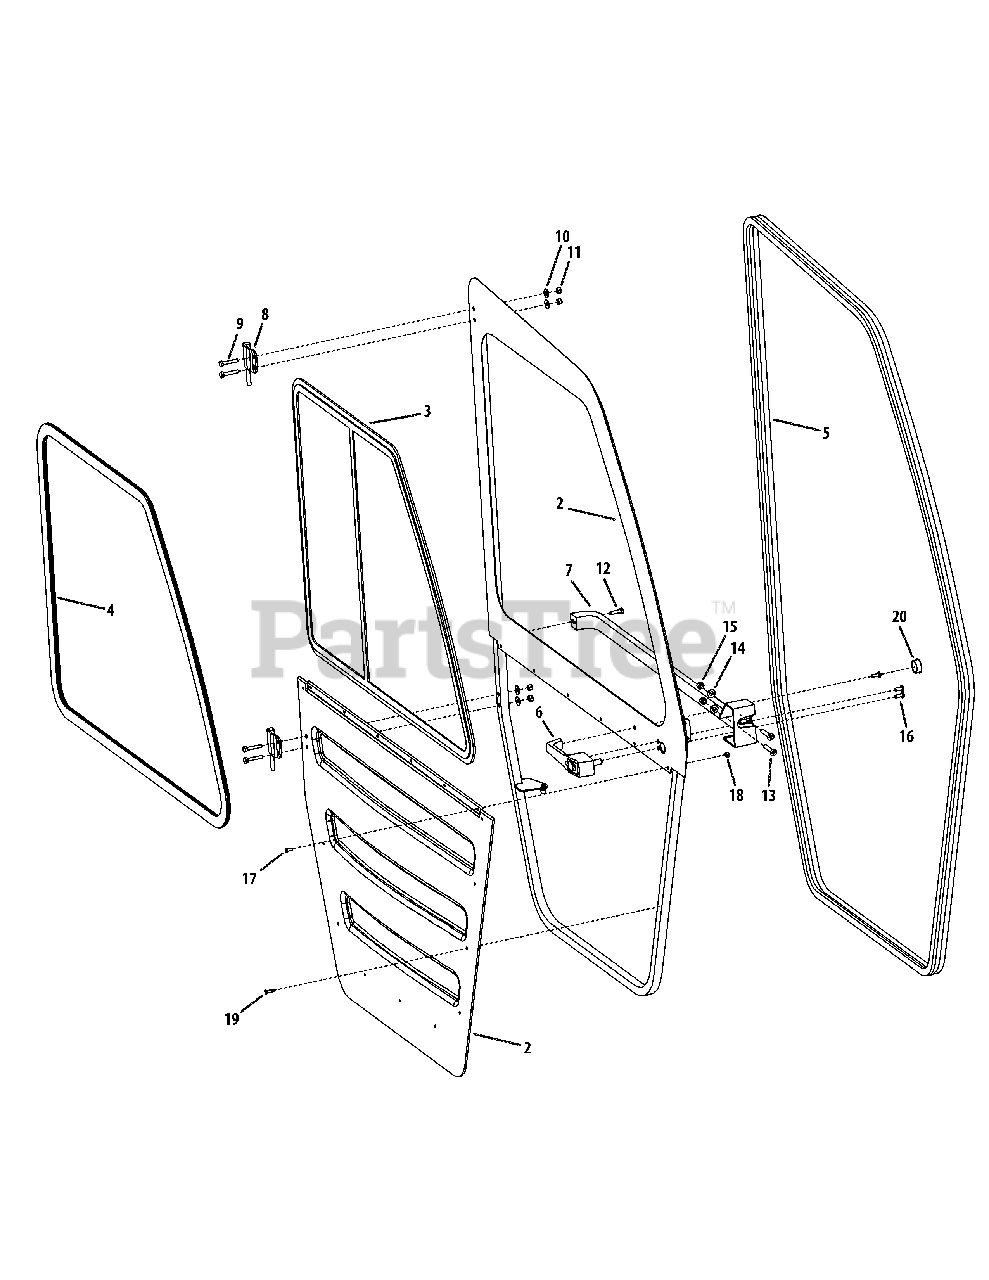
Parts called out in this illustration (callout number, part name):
2	Door Frame with lower Panel, RH
3	Sliding Window, Temp. Glass
4	Window Mounting Rubber - 10'
5	1-1/2" Side Bulb & 2 Wipers - 15'
6	Outside Handle (Set Of 2)
7	Door Latch RH - Non Locking
8	Tube Frame Hinge, RH
